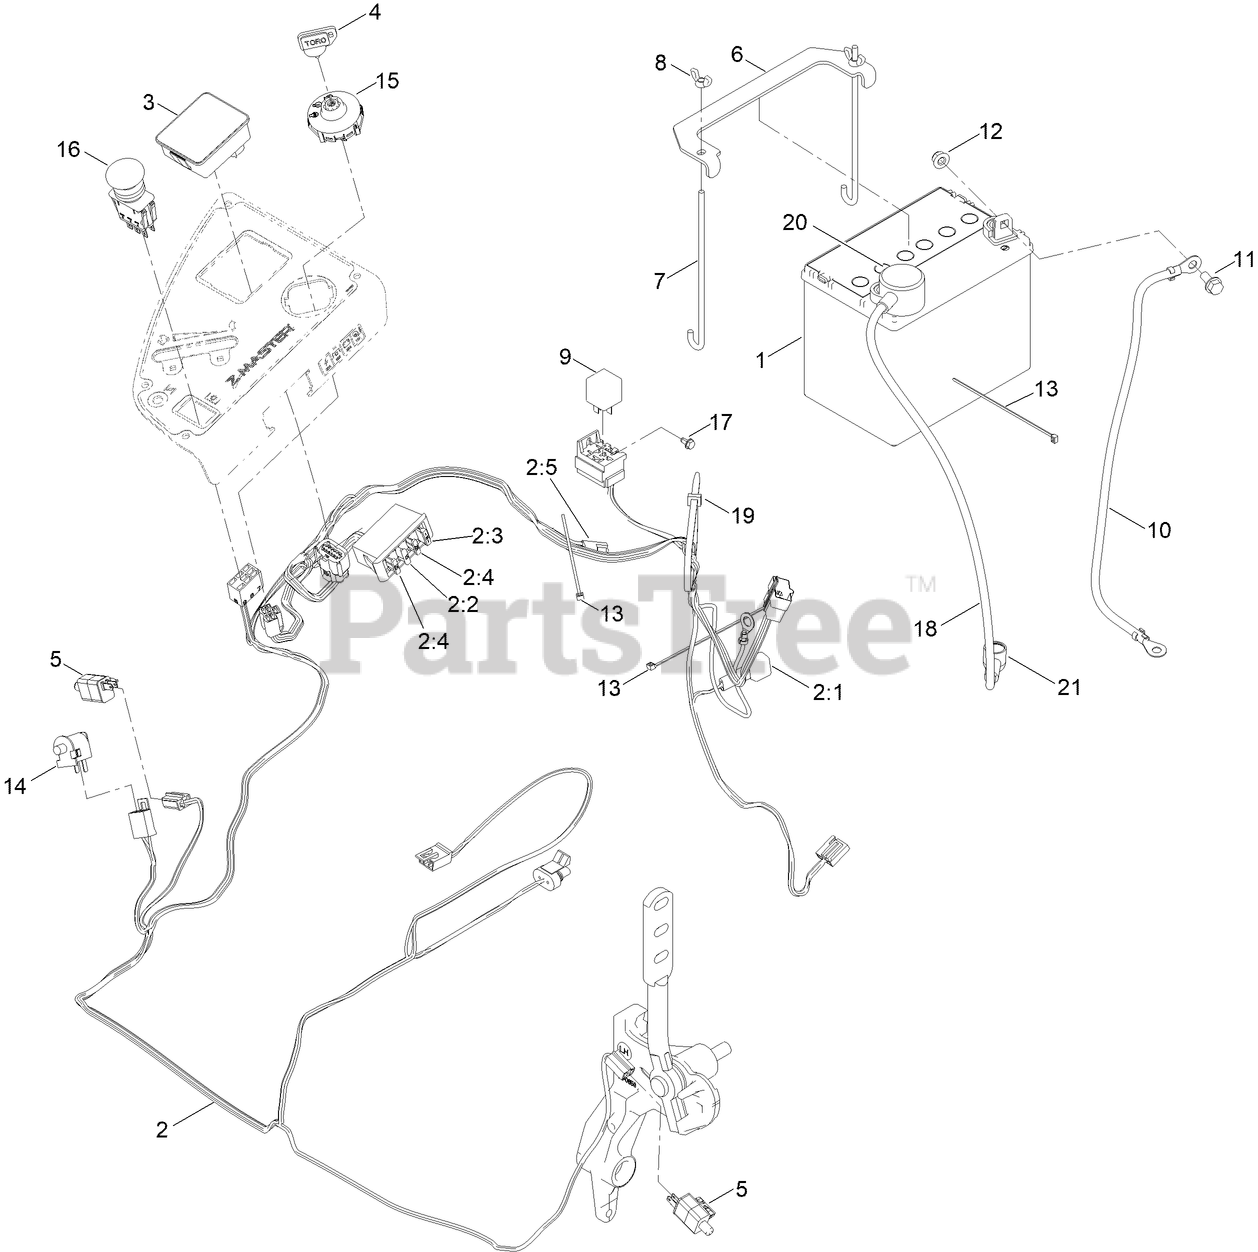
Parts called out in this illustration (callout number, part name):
1	BATTERY-DRY
2	HARNESS-WIRE, MAIN
2:2	FUSE-BLADE, 10 AMP
2:3	FUSE-BLADE, 15 AMP
2:4	FUSE-BLADE, 25 AMP
2:5	CAP-PLUG
3	FUEL/HOUR METER ASM
4	KEYS-IGNITION (SPARE PAIR)
4	KEY-IGNITION
5	SWITCH
6	STRAP-TIE DOWN, BATTERY
7	BOLT-HOLDDOWN
8	WINGNUT
10	CABLE-BATTERY, NEGATIVE
11	SCREW-HHF
12	NUT-HF, NI
13	TIE-CABLE
14	SWITCH-BAIL
15	SWITCH-IGNITION
16	SWITCH, PTO 10A
17	SCREW-HWH
18	CABLE-BATTERY, POSITIVE
19	TIE-CABLE
20	INSULATOR-BATTERY
21	INSULATOR-SOLENOID
